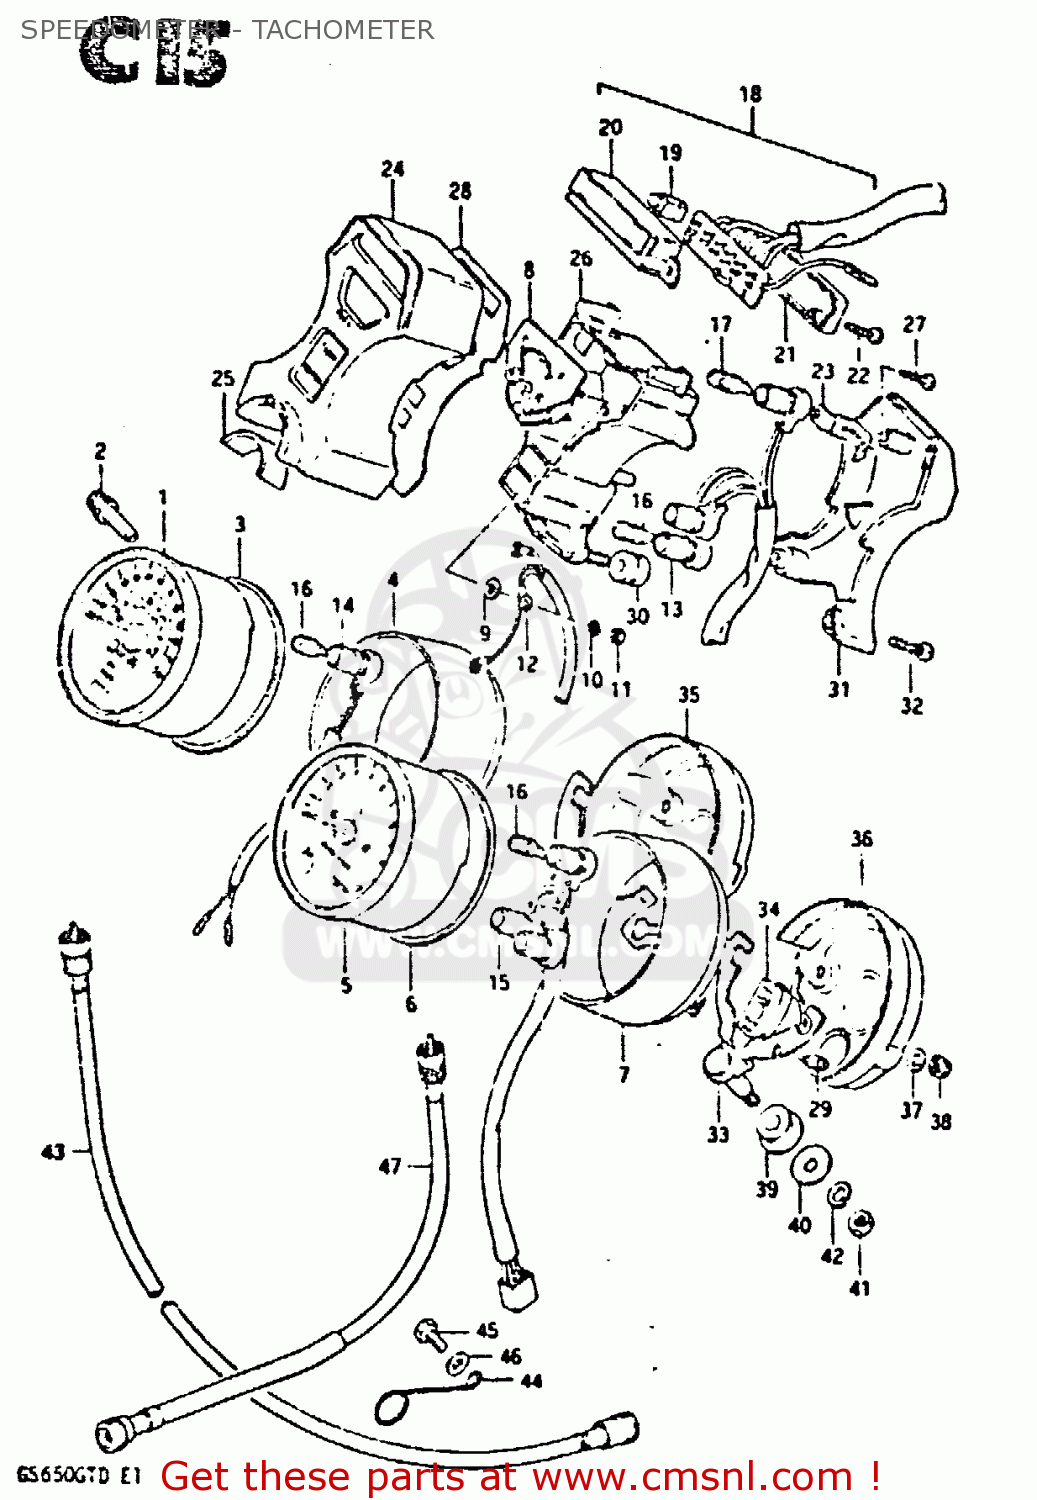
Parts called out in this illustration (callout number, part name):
1	SPEEDOMETER (MILE/KILO)
2	KNOB
3	CUSHION,SPEEDOMETER
4	COVER,SPEEDOMETER
5	TACHOMETER
6	CUSHION,SPEEDOMETER
7	COVER,TACHOMETER
8	METER,FUEL
9	WASHER,FUEL METER
10	LOCK WASHER
11	NUT 3MM
12	LEAD WIRE,FUEL METER
13	SOCKET
14	SOCKET,SPEEDOMETER
15	SOCKET,TACHOMETER
16	BULB(12V3.4W,T10)
17	BULB(12V1.7W,T10,WB121)
18	INDICATOR ASSEMBLY,GEAR POSITION
19	BULB(14V1.12W,BQ041-32503B)
20	CASE,GEAR INDICATOR
21	COVER,LWR
22	SCREW,GEAR INDICATOR
23	CLAMP,CORD
24	CASE,PILOT BOX
25	SEAL,IGNITION SWITCH
26	CASE,PILOT BOX,INNER
27	SCREW,INDICATOR
28	PLATE,PILOT BOX
29	CUSHION,METER
30	CUSHION,PILOT BOX
31	COVER,PILOT BOX,UNDER
32	SCREW
33	BRACKET,COMBINATION METER
34	CUSHION
35	COVER,METER,UNDER
36	COVER,TACHOMETER
37	WASHER
38	NUT
39	CUSHION,METER BRACKET
40	WASHER (8.5X20X1.6)
41	NUT
42	LOCK WASHER
43	CABLE ASSEMBLY,SPEEDOMETER
44	CLAMP,SPEEDOMETER CABLE
45	BOLT, UPPER
46	WASHER
47	CABLE ASSEMBLY,TACHOMETER
